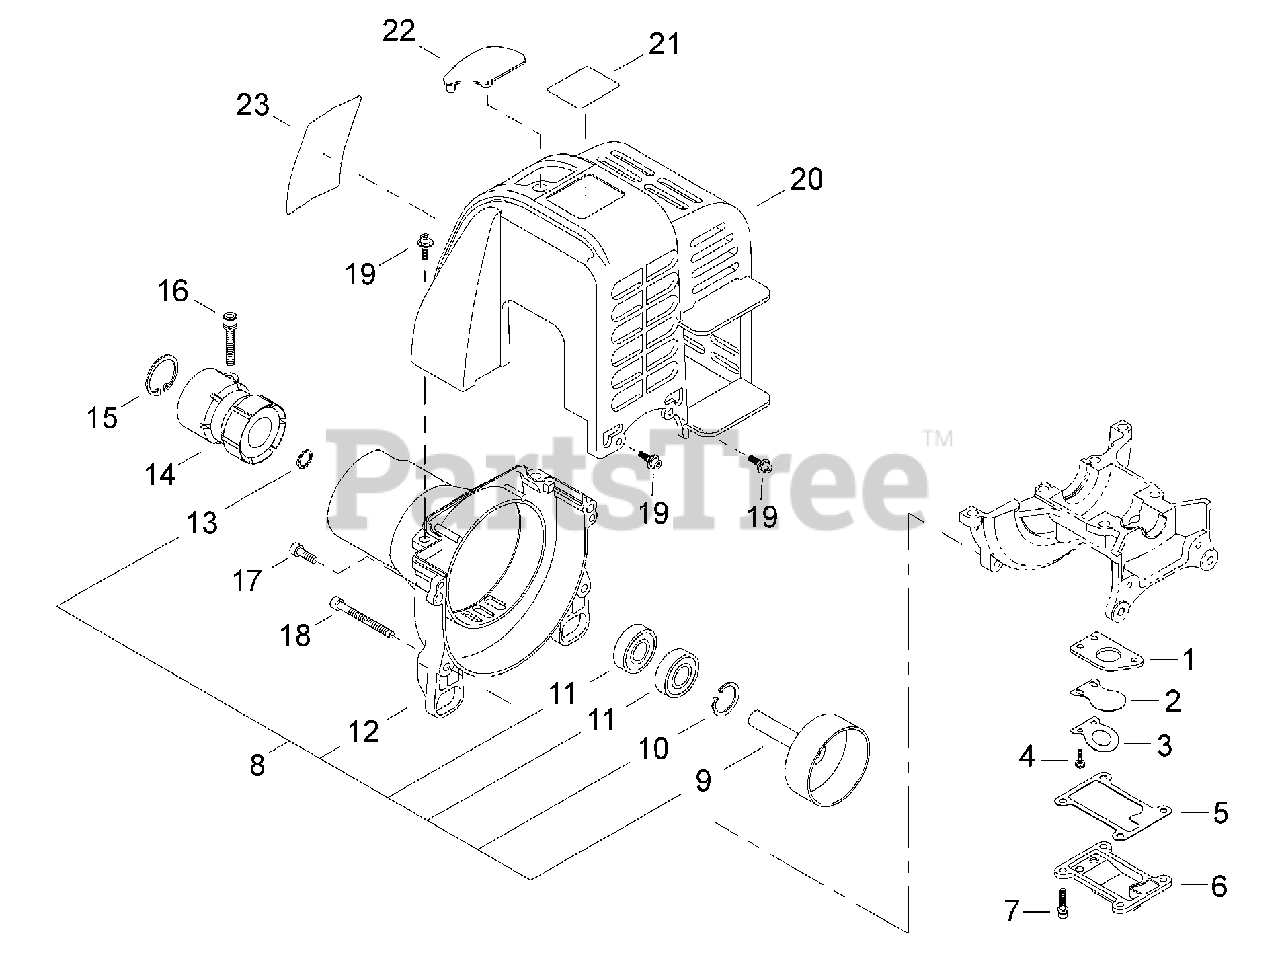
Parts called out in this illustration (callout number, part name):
1	PLATE, REED BACKING
2	VALVE, REED
3	STOP, REED VALVE
4	SCREW M3×10
5	GASKET, REED VALVE
6	COVER, REED VALVE
7	BOLT M4×12
8	COVER ASSY, FAN
9	DRUM, CLUTCH
10	RING, SNAP Ø26
11	BEARING, BALL 6000ZZ
12	COVER, FAN
13	RING, SNAP WR10
14	CUSHION, AV
15	RING, SNAP Ø40
16	BOLT M5×22
17	BOLT 5×16
18	BOLT M5×45
19	BOLT M4×16
20	COVER, ENGINE
21	LABEL, LE2510 ID
22	COVER, SPARK PLUG
23	LABEL, C4 SHINDAIWA
